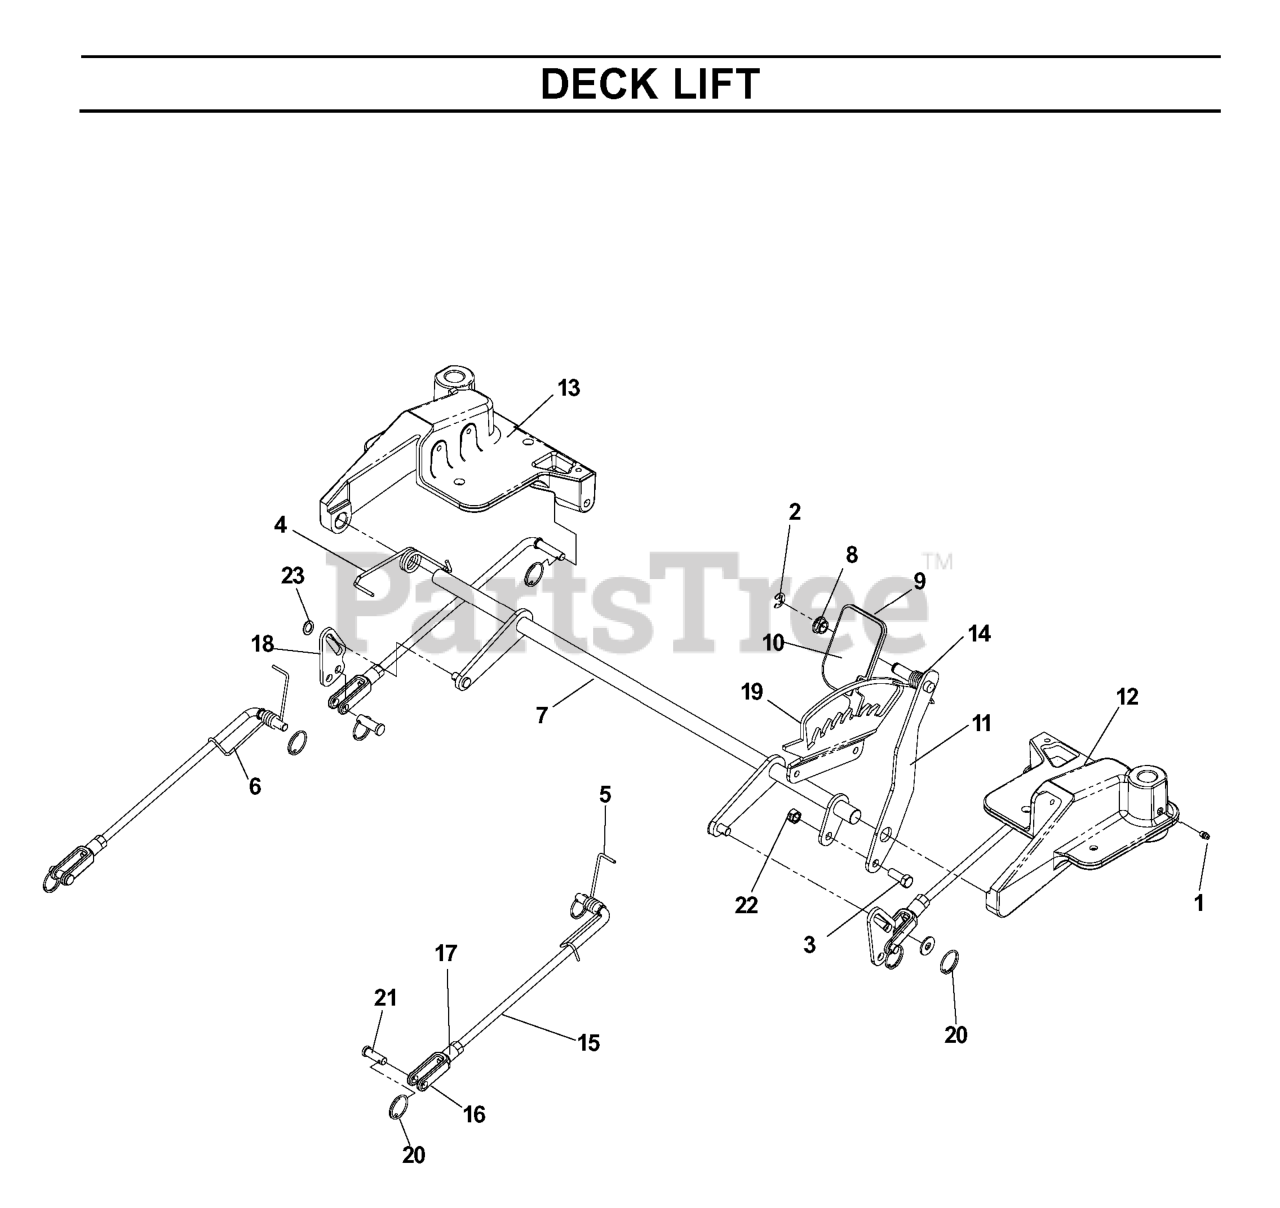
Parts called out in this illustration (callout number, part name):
2	E-RING 1/2 (2 2)
3	HEX BOLT 3/8 X 1"
4	TORSION SPRING, DECK LIFT
5	SPRING, DECK ROD RIGHT
6	SPRING, DECK ROD LEFT
7	DECK LIFT ASM PAINTED
8	BUSHING, FLANGED NYLON
9	FOOT PEDAL
10	FOOT PAD, NON-SLIP
11	LIFT FOOT, LEVER WELDED
12	CASTER CASTING, RIGHT, PAINTED
13	CASTER CASTING LEFT, PAINTED
14	SPRING, PEDAL, LIFT
15	DECK LIFT ROD
16	YOKE-3/8-24 PLTD
18	CONNECTOR, DECK LIFT
19	HEIGHT PLATE, DECK
21	CLEVIS PIN 3/8 X 1 1/8
22	NUT 3/8C CENTERBLOCK
23	WASHER 5/16 FLAT
